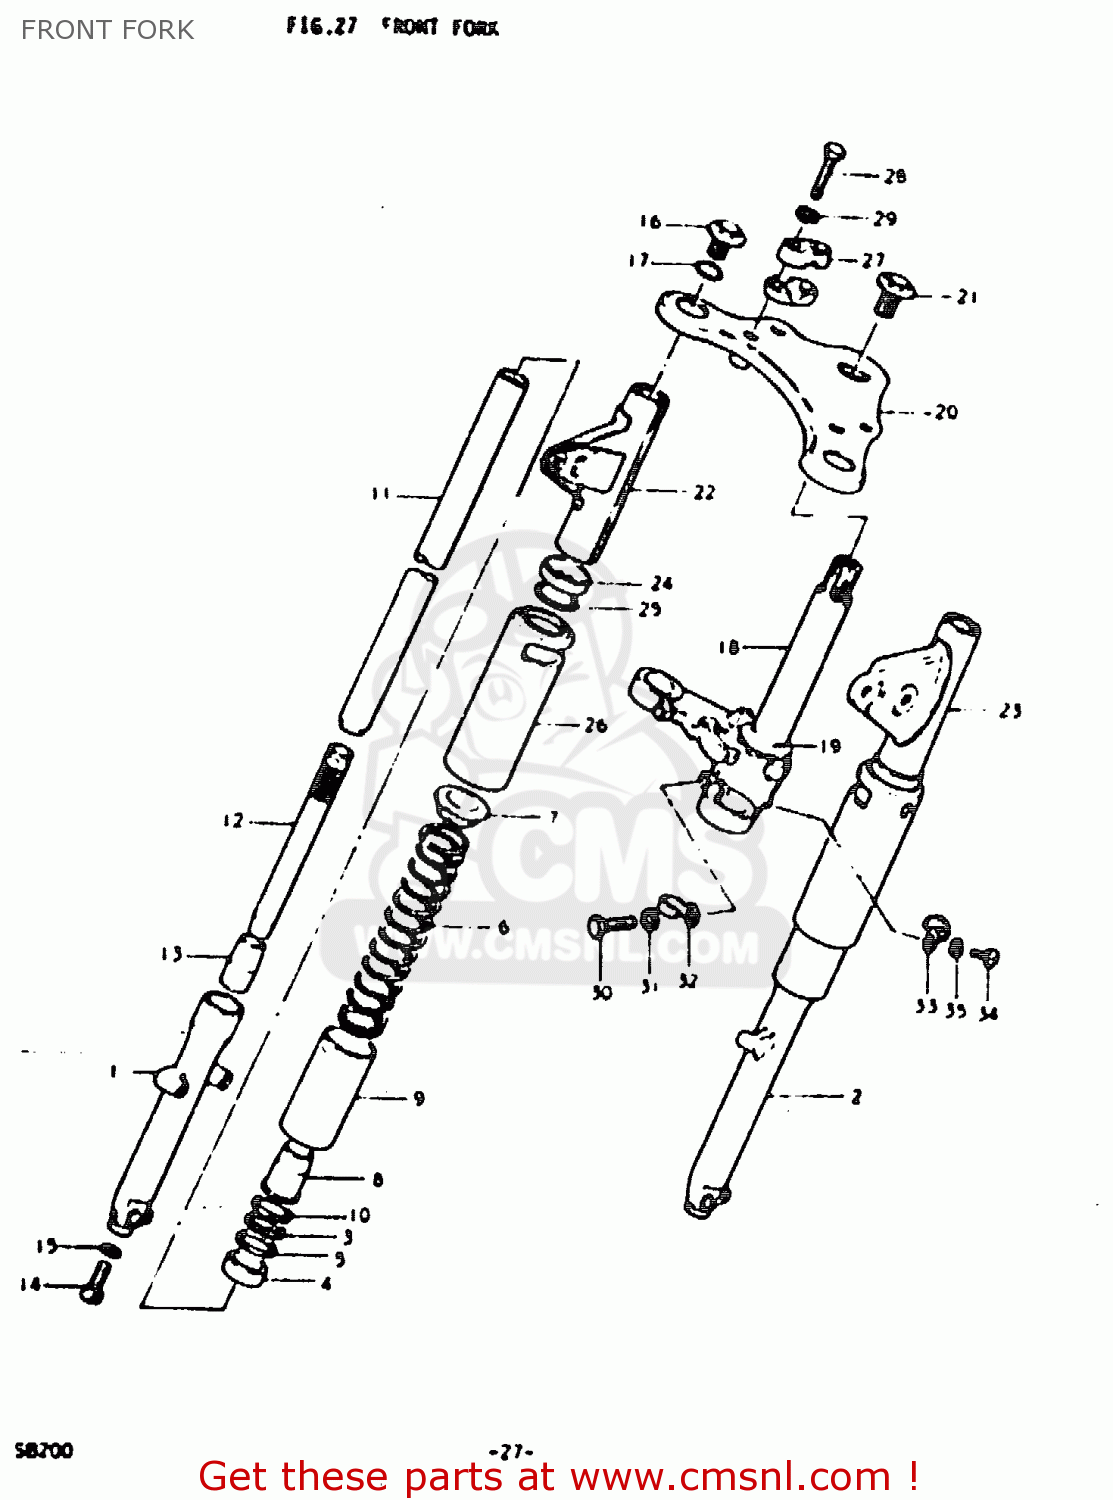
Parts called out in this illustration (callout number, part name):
1	OUTER TUBE, RH
2	OUTER TUBE, LH
3	RING,SNAP
4	OIL SEAL,FRONT FORK
5	WASHER,FRONT FORK
6	SPRING
7	GUIDE, SPRING UPPER
8	DUST SEAL
9	COVER, OUTER TUBE
10	WASHER,FRONT FORK
11	INNER TUBE
12	CYLINDER
13	PIECE,OIL LOCK
14	BOLT,FORK CYLINDER(10X25)
15	GASKET (NAS)
16	CAP, INNER TUBE
17	O RING
18	STEM
19	RACE,STEERING OUTER LWR
20	STEM HEAD
21	BOLT
22	BRACKET, HEADLAMP RH
23	BRACKET, HEADLAMP LH
24	GUIDE,BRACKET
25	CUSHION,HEAD LAMP BRACKET
26	COVER, OUTER
27	HOLDER,HANDLE(BLACK)
28	BOLT
29	LOCK WASHER
30	BOLT,FR FORK LWR(12X33)
31	WASHER,LOCK 12
32	CLIP
33	CLIP,BRAKE CABLE
34	SCREW
35	LOCK WASHER
